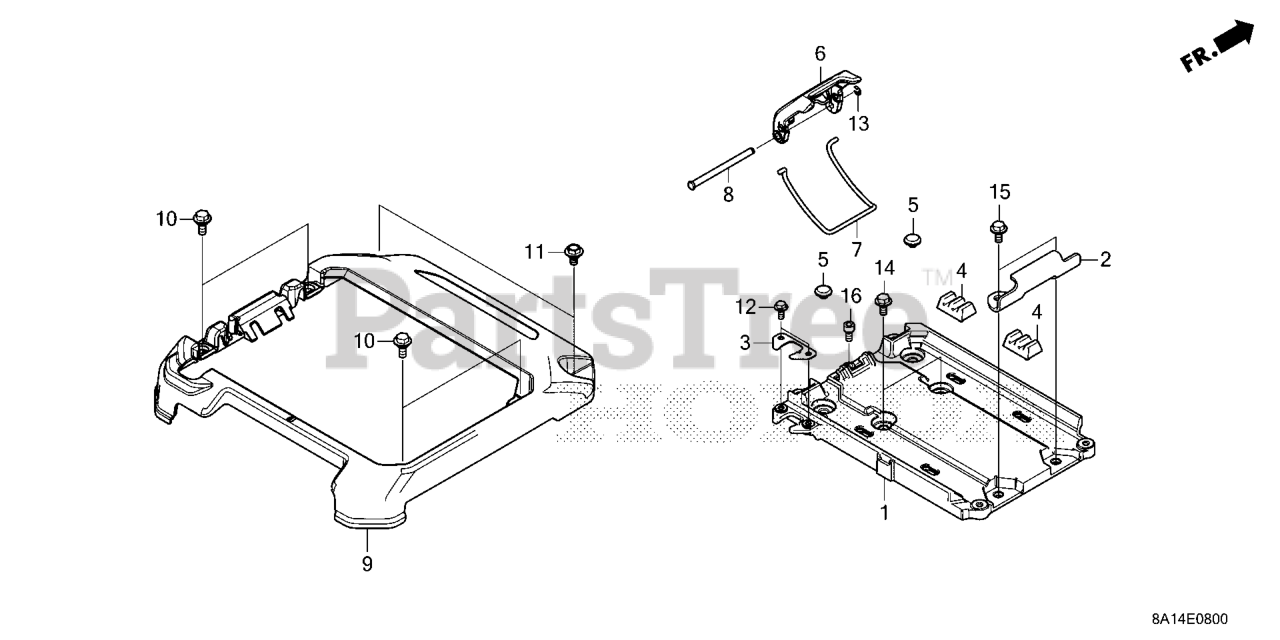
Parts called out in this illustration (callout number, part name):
1	TRAY, BATTERY
2	HOOK, BATTERY
3	STAY, CONNECTOR
5	CAP, HOLE (8MM)
6	LEVER *NH283*
7	WIRE, FASTENER
8	PIN, LOCK LEVER
9	COVER *R280*
9	COVER *NH1*
10	BOLT, SPECIAL (6X16)
11	BOLT, SPECIAL (6X12)
12	BOLT, FLANGE (5X12)
13	E-RING (4MM)
14	BOLT, FLANGE (8X16)
15	BOLT, FLANGE (8X20)
16	BOLT, SOCKET (6X12)
